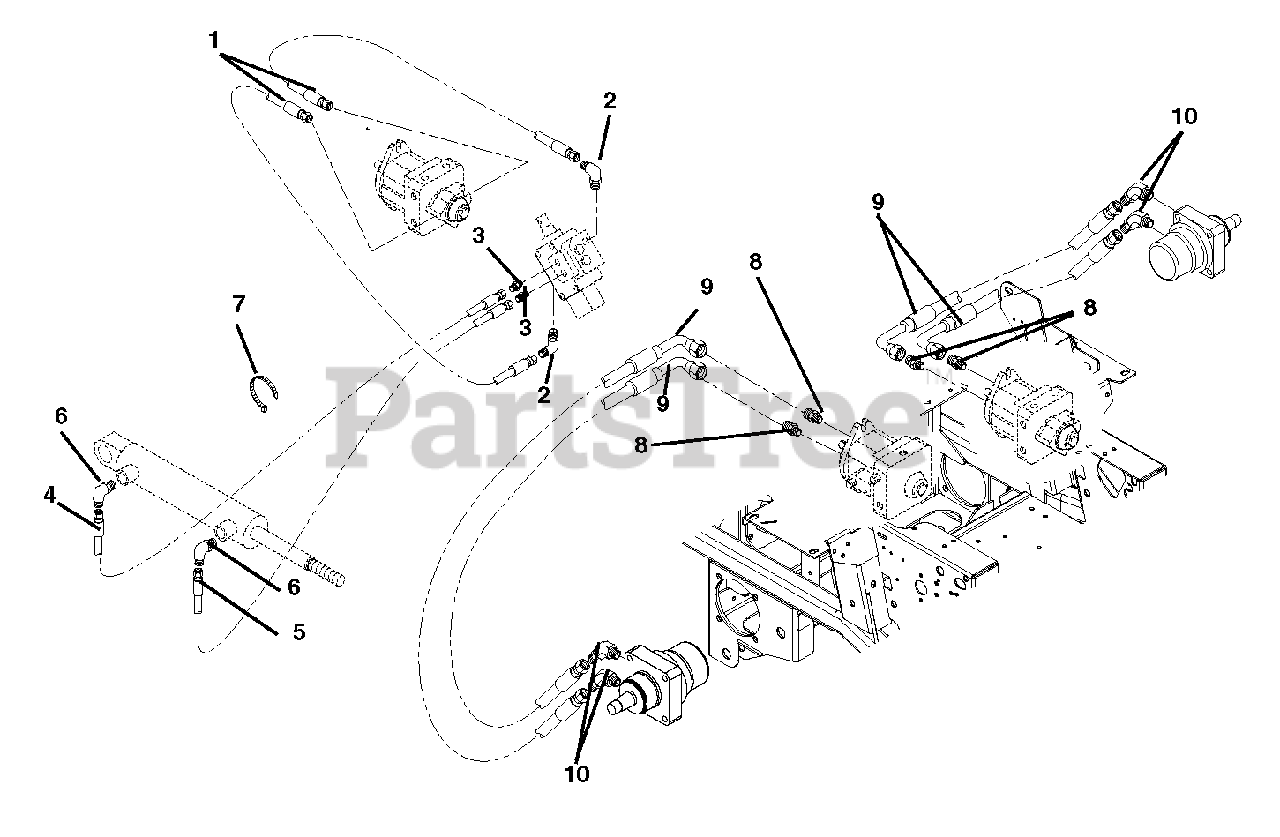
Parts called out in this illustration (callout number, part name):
1	Hose, Hydraulic
2	Fitting, Hydraulic Elbow
3	Adapter (4-6F5OLO)
4	Hose, Hydraulic
5	Hose, Hydraulic
6	Fitting, Hydraulic (4 C5OLO)
7	Cable Tie
8	Adapter, Face Seal 8 x 8 .50 O-Ring
9	Hose, Hydraulic .50
10	Adapter, Hydraulic Steel .875 to .75
